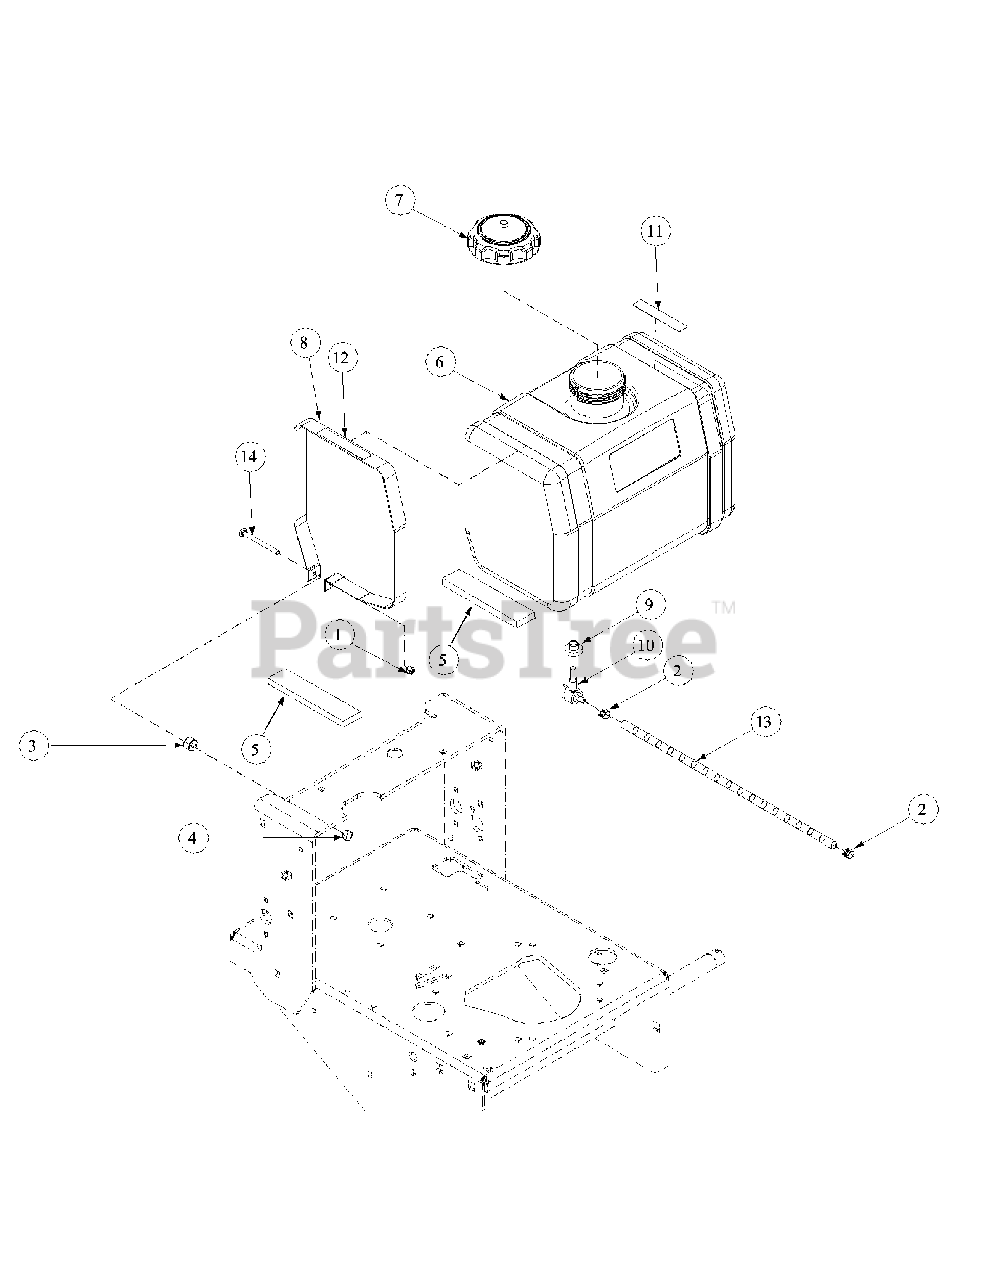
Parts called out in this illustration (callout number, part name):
1	Lock Nut, Nylon Insert, 1/4-20
2	Uni-Clamp
4	Nut, 1/4 -20
5	Rubber Stop Pad
6	Fuel Tank
7	Fuel Cap, 3.5
8	Fuel Tank Strap
9	Grommet Fuel Tank
10	Shut Off Fuel Tank
11	Label, Mower Warning Turn Off Engine
12	Label, Fuel Valve Instruction Info.
13	Fuel Hose, 18" x .25 ID
14	Carriage Bolt, 1/4-20 x 3.00
